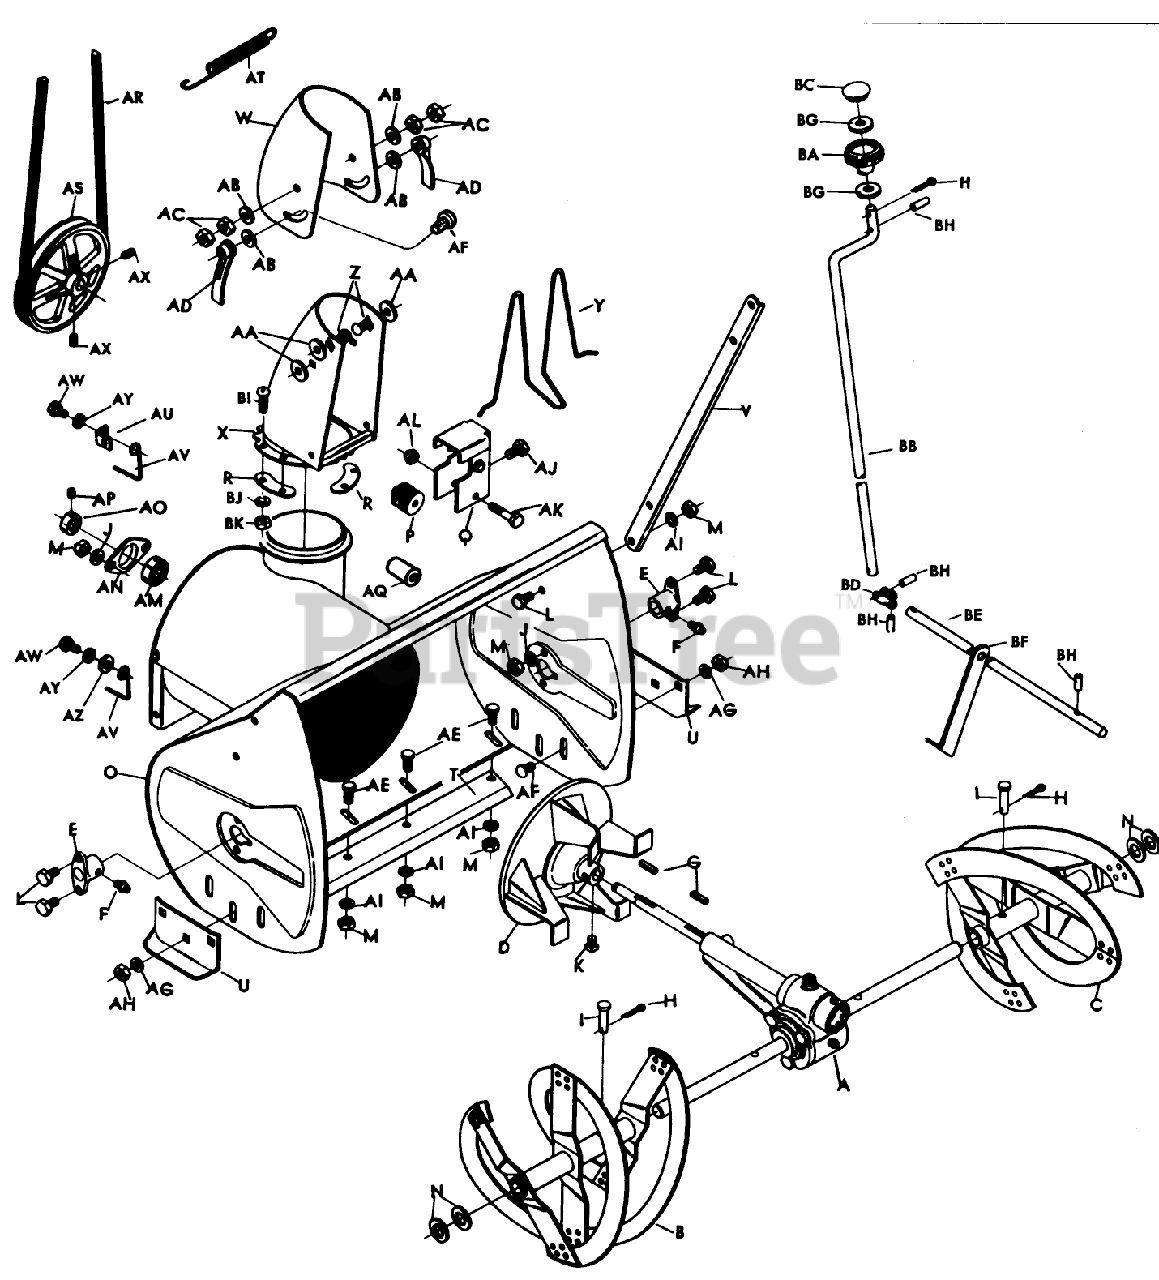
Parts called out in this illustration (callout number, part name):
A	Gear Case Ass-y,
H	1/8 x 3/4 Cotter Pin, Pl.
J	5/16 Lock Washer
K	3/8-16 x 1/2 Sq. Hd. Set Screw, Cup Pt.
L	5/16-18 x 3/4 Hex. Hd. Cap Screw, Pl.
M	5/16-18 5/16-18 Hex. Nut, Pl.
O	Auger Wrap Assembly, 5 H.P. Units
W	Deflector
AA	1/2 Flat Washer, Pl.
AB	3/8 Flat Washer, Pl.
AC	3/8-16 Hex. Jam Nut, Pl.
AF	3/8-16 x 3/4 Carriage Bolt, Pl.
AG	3/8 Lock Washer, Pl.
AH	3/8-16 Hex. Nut, Pl.
AI	5/16 Lock Washer, Pl.
AJ	5/16-18 x 1 1/4 Hex. Hd. Cap Screw, Pl. H.T.
AK	1/4-20 x 2 Hex. Hd. Cap Screw, Pl.
AL	1/4-20 Cone Lock Nut, Pl.
AP	1/4-20 x 1/4 Socket Set Screw
AW	1/4-20 x 3/4 Hex. Hd. Cap Screw, Pl.
AX	3/8-16 x 3/4 Sq. Hd. Set Screw, H.T. Pl.
AY	1/4 Lock Washer, Pl.
AZ	1/4 Flat Washer, Pl.
BG	3/8 S.A.E. Flat Washer, Pl.
BH	1/8 x 3/4 Roll Pin, Pl.
BI	#8-32 x 3/8 Slotted Rd. Hd. Machine Screw, Pl.
BJ	#8 Lock Washer, Pl.
BK	#8-32 Hex. Nut Pl.
